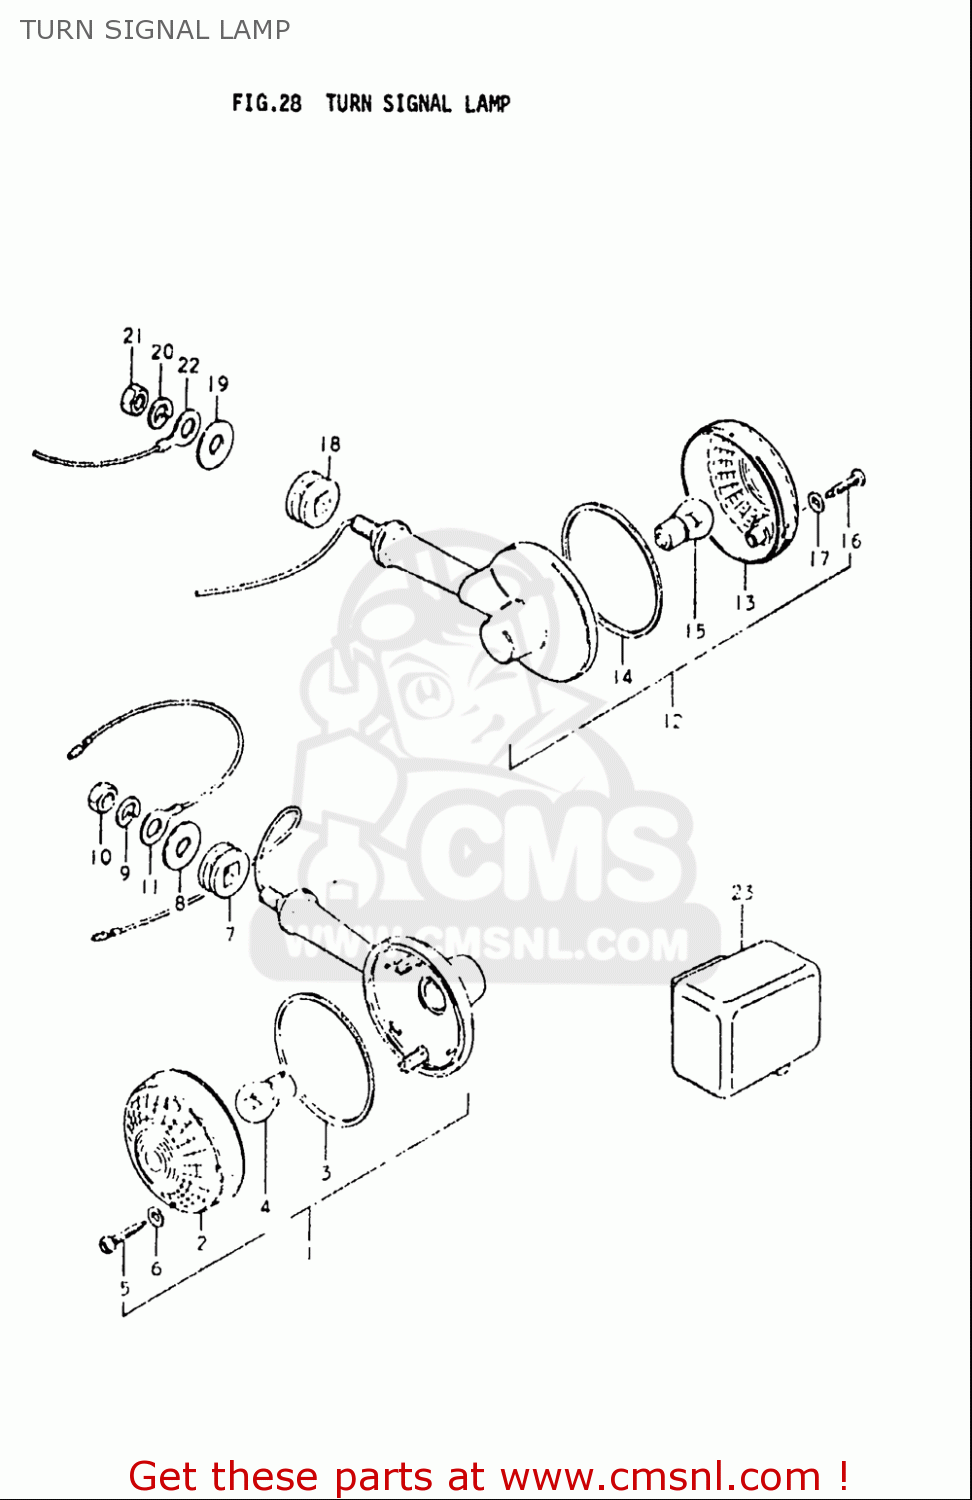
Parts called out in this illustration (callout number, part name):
1	LAMP ASSY,RR TURNSIGNAL
2	LENS
3	GASKET (NAS)
4	BULB(12V23W,STANLEY,A4577A)
5	SCREW
6	GASKET (NAS)
7	CUSHION
8	WASHER (8.5X30X2.3)
9	WASHER,LOCK
10	NUT
11	LEAD WIRE,EARTH
12	LAMP ASSY,RR TURNSIGNAL
13	LENS
14	GASKET (NAS)
15	BULB(12V23W,STANLEY,A4577A)
16	SCREW
17	GASKET (NAS)
18	CUSHION
19	WASHER (8.5X30X2.3)
20	WASHER,LOCK
21	NUT
22	WIRE,REAR TURN SIGNAL EA
23	RELAY ASSY,TURNSIGNAL
